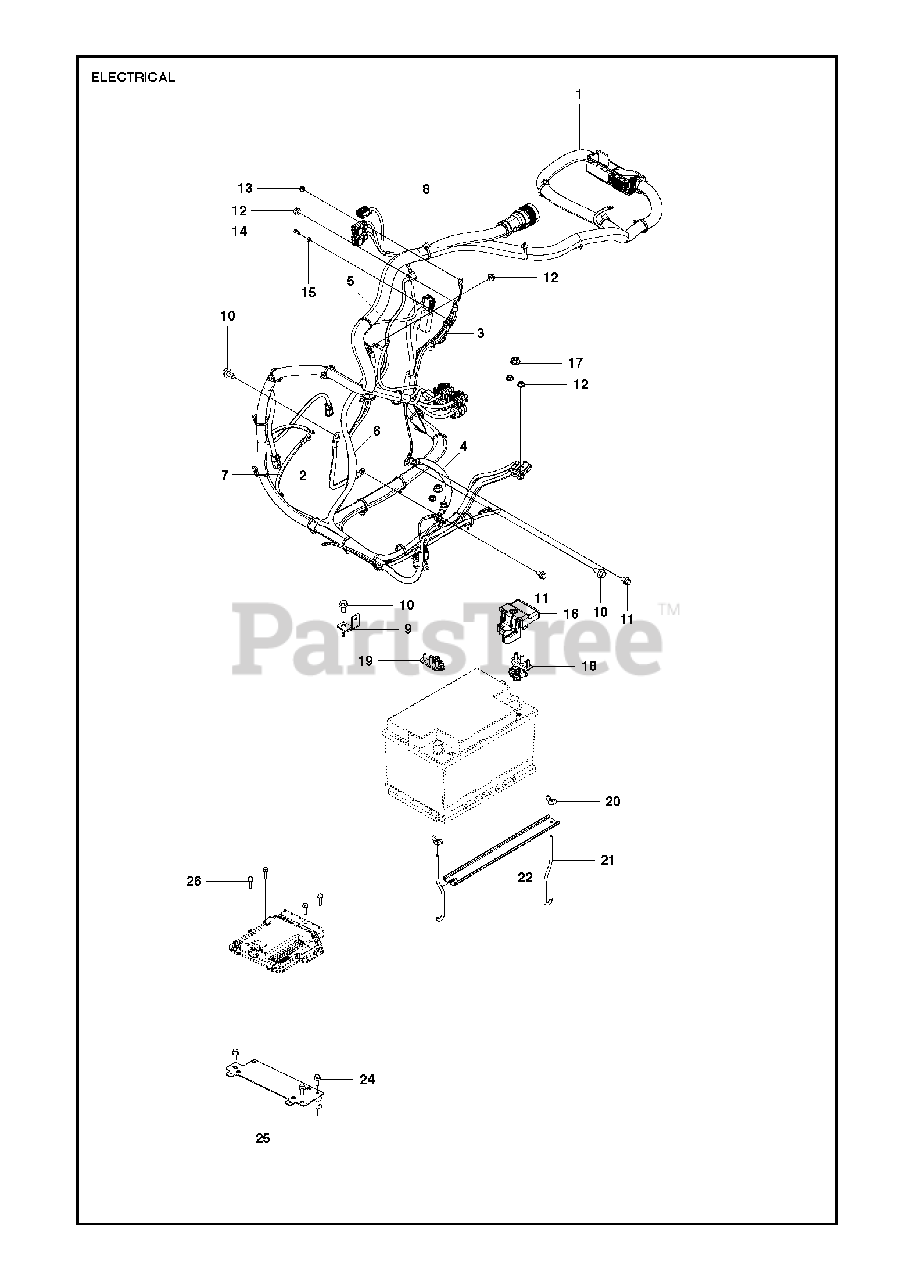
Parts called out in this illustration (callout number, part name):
2	HARNESS ASSYHydraulic Pump - Chassie
3	HARNESS ASSYBATT + Relay Box
4	HARNESS ASSYGROUND - Chassie
5	HARNESS ASSYBATT + Starter
6	HARNESS ASSYBATT + Generator
7	HARNESS ASSYBATT + Hydraulic Pump
10	SCREW EHHFT
12	HEXAGON NUT FLANGE
13	HEXAGON NUT FLANGE
14	SCREW EHHM
15	WASHER
17	HEXAGON NUT FLANGE
